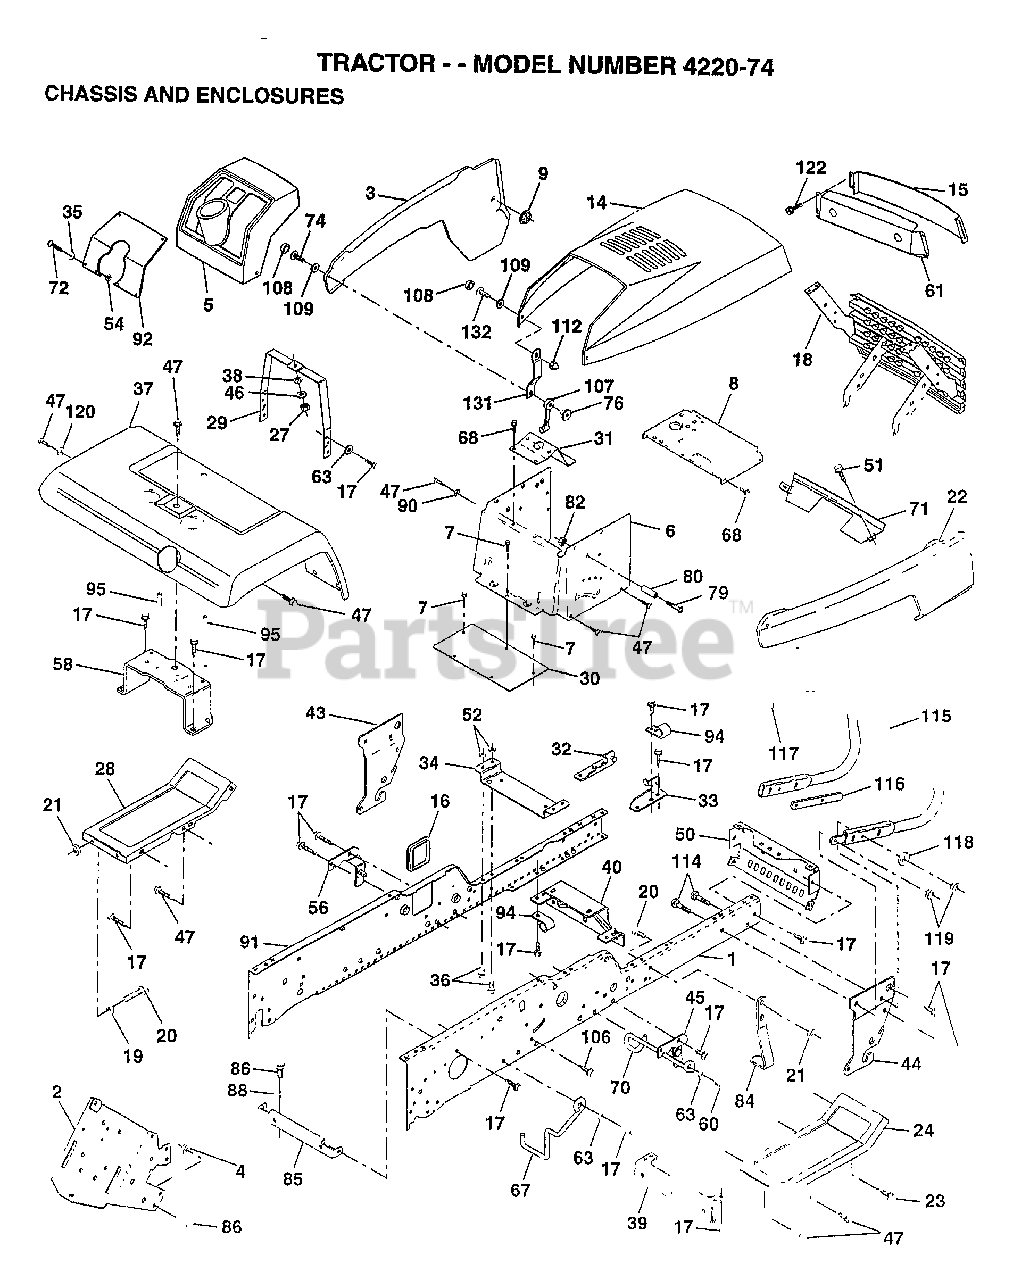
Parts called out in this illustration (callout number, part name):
1	"RAIL,FRAME RH"
2	DRAWBAR GT
3	PANEL ASM SIDE LH
4	NUT.7/16
5	DASHBOARD BLACK
6	DASH LOWER
7	SCREW
8	SUPPORT.DASH.BTRY
9	PAL NUT LT
15	LENS.BAR.CLEAR
16	COVER ACCESS
17	SCREW
19	WASHER
20	BOLT
22	PANEL ASM SIDE RH
23	SCREW GTV
24	FOOTREST.RH.LT/GT
28	FOOTREST.LH.LT/GT
29	DASH.SUPT.YP/HUSQ
30	SADDLE.HYDRO.95
31	BRAKET.SUPT.STEER
32	BRACKET ASM FRAME
33	BRACKET ASM FRAME
34	BRACKET.ENG.SUPT.
35	WASHER
36	BOLT
38	LOCKWASHER
39	BRACKET.AXLE.FRT.
40	"BRKT SUPPORT,AXLE"
43	BRACKET.SUS.FT.LH
44	BRACKET.SUS.FT.RH
45	BRACKET ASM., SUSP CHASSIS RH
46	WASHER PM
47	SCREW LT
50	"BRKT CHASSIS,FRNT"
51	SCREW CRT
54	NUT
56	BRACKET.SUSP.LH.
58	BRKT.ASM.FENDER
60	SCREW
61	BEZEL.ASM.
63	WASHER
67	"GUIDE BELT, T/A"
68	SCREW LT
70	GUIDE.BELT.MID.SP
71	STRAP.GRILLE.424
72	SCREW
74	SCREW
76	WELDNUT
79	SCREW
80	SPACER LT
84	STOP.OVER.CENTER
86	BOLT
88	LOCKWASHER
90	LOCKWASHER
91	"RAIL FRAME,LH"
92	"PLATE-DASH,SLKSCR"
94	CLIP GTV
95	NUT-PUSH YT
107	HOOD LATCH T
108	SNAP CAP LT
109	CAP WASHER SNAP NAT
112	ACORN NUT RB
114	BOLT.3/8-14X1.25
115	BUMPER.ASM
116	BRACKET.EXT.BUMP.
117	PLUG.PLASTIC
118	WASHER
120	WASHER HYT
131	BKT.SPT.HOOD/PANL
132	SCREW.10-24X3/8.
